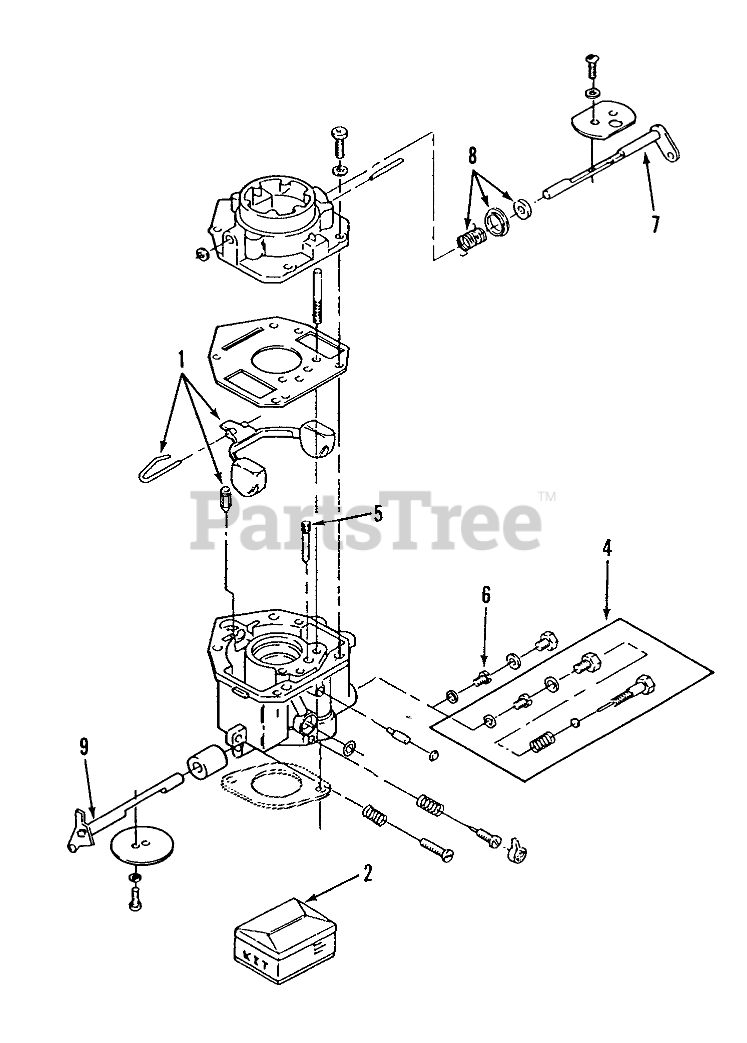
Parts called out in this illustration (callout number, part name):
1	Float Kit (Includes Float, Pin and Valve)
2	Repair Kit (Includes Screw and Plug Package, Gasket Package, Float Valve, Idle Adjustment Needle and Spring, Mounting Gaskets, Idle Limit Cap)
4	FIXED-JET
5	IDLE-JET
6	POWER JET
7	Choke Shaft Kit (Includes Choke Valve, Valve Set Screw and Air Filter)
8	Choke Lever Kit (Includes Choke Lever Ring, Choke Spring and Choke Collar)
9	Throttle Shaft Kit (Includes Valve Set Screw, Air Filter and Throttle Valve
